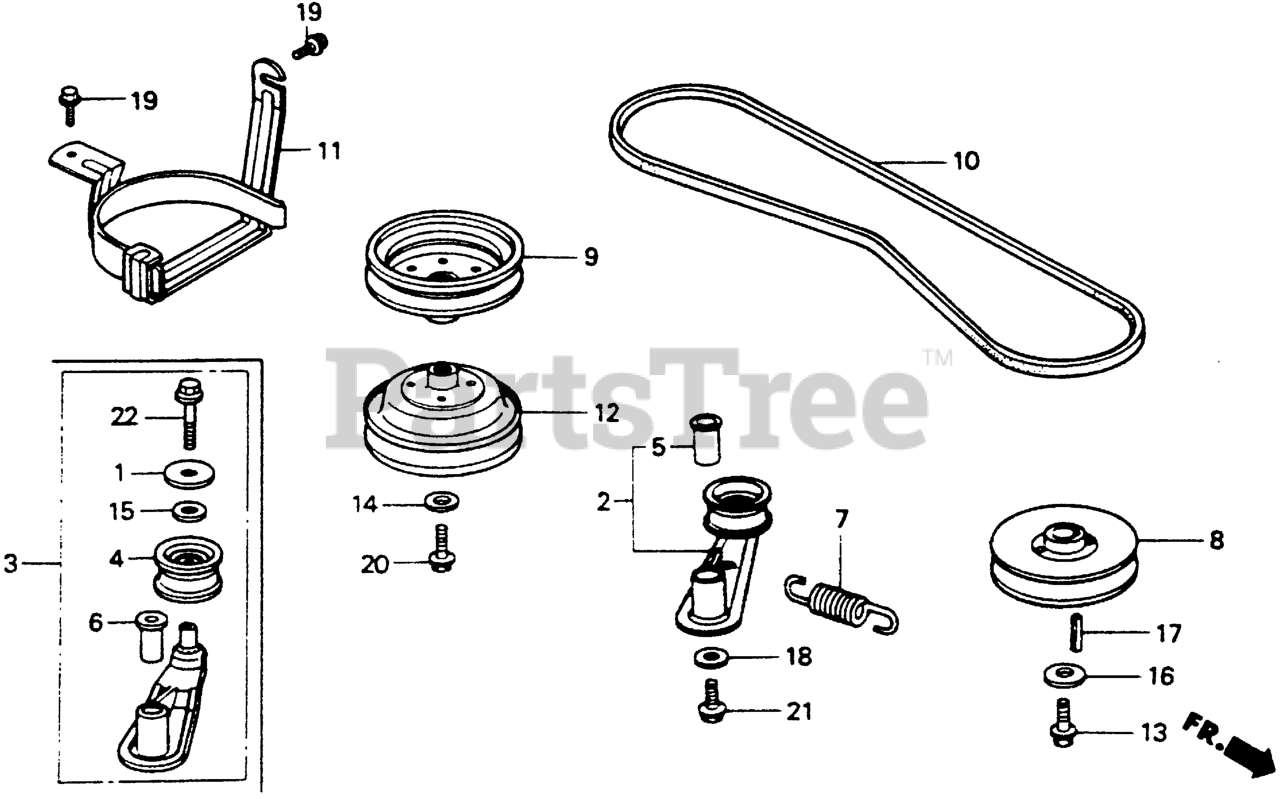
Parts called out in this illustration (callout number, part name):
1	GUARD, TENSION ROLLER
2	ARM ASSY., TENSIONER
3	ARM ASSY., TENSIONER
4	ROLLER, TENSIONER
5	BUSH (15X19X39.5)
6	BUSH (15X19X39.5)
7	SPRING, PRIMARY BELT TENSION
8	PULLEY, ENGINE (120MM)
9	PULLEY, DRIVEN
10	V-BELT, PRIMARY (SB-51)
11	STOPPER, BELT (NOT AVAILABLE)
12	PULLEY, TRANSMISSION
13	BOLT, FLANGE (7/16"X28)
14	WASHER, SPECIAL (28X8.5X4.0)
15	WASHER (6X17)
16	WASHER, PLAIN (12MM)
17	KEY (6.3X6.3X30)
18	WASHER, PLAIN (10MM)
19	BOLT, FLANGE (6X12)
20	BOLT, FLANGE (8X20)
21	BOLT, FLANGE (10X20)
22	BOLT, FLANGE (6X16)
